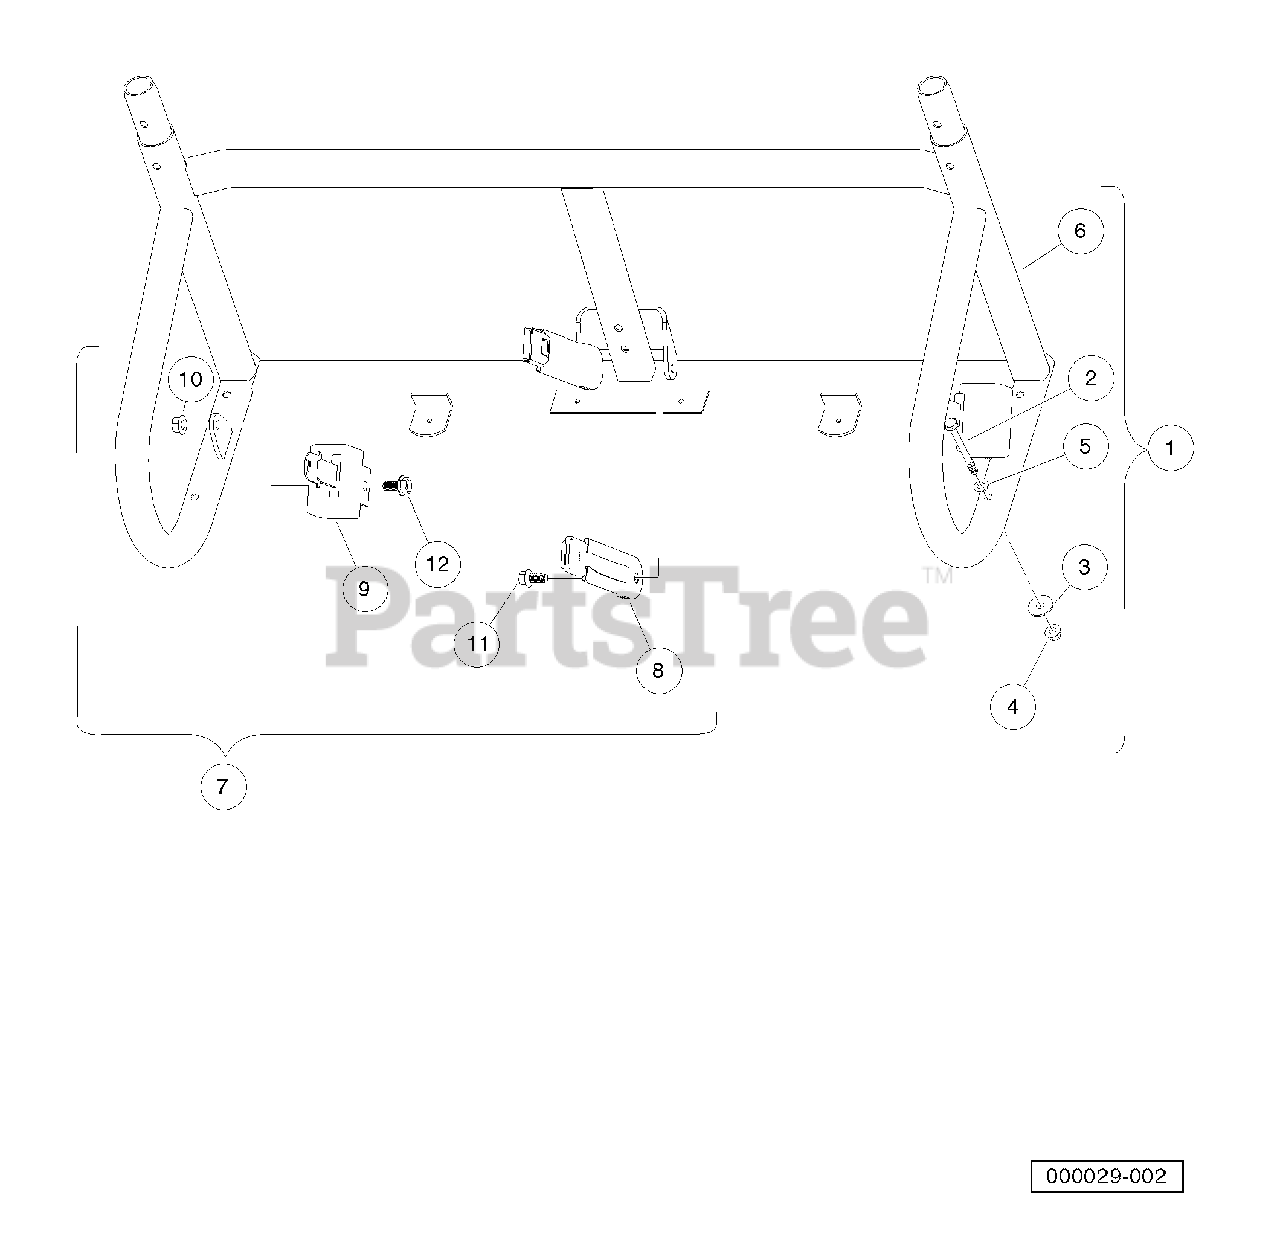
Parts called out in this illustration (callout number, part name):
1	Instl, Rops, Lower
2	Bolt, M10x1.50x100
3	Washer Hard,m10
4	Nut Flg M10 X 1.5 Mech Def
5	Washer, Hard, M10, Zn-Ni/Blk
6	Weldment,seat Support,hs,rops
7	Instl, Seat Belt, Restyle
8	Buckle, Seat Belt with Sleeve
9	Retractor, Seat Belt
10	Ln Flg, M12 X 1.75, Md, Black
11	Screw,m12x1.75x30 Thd Form Blk
12	Bolt Flg, M12x1.75 X 25 Black
